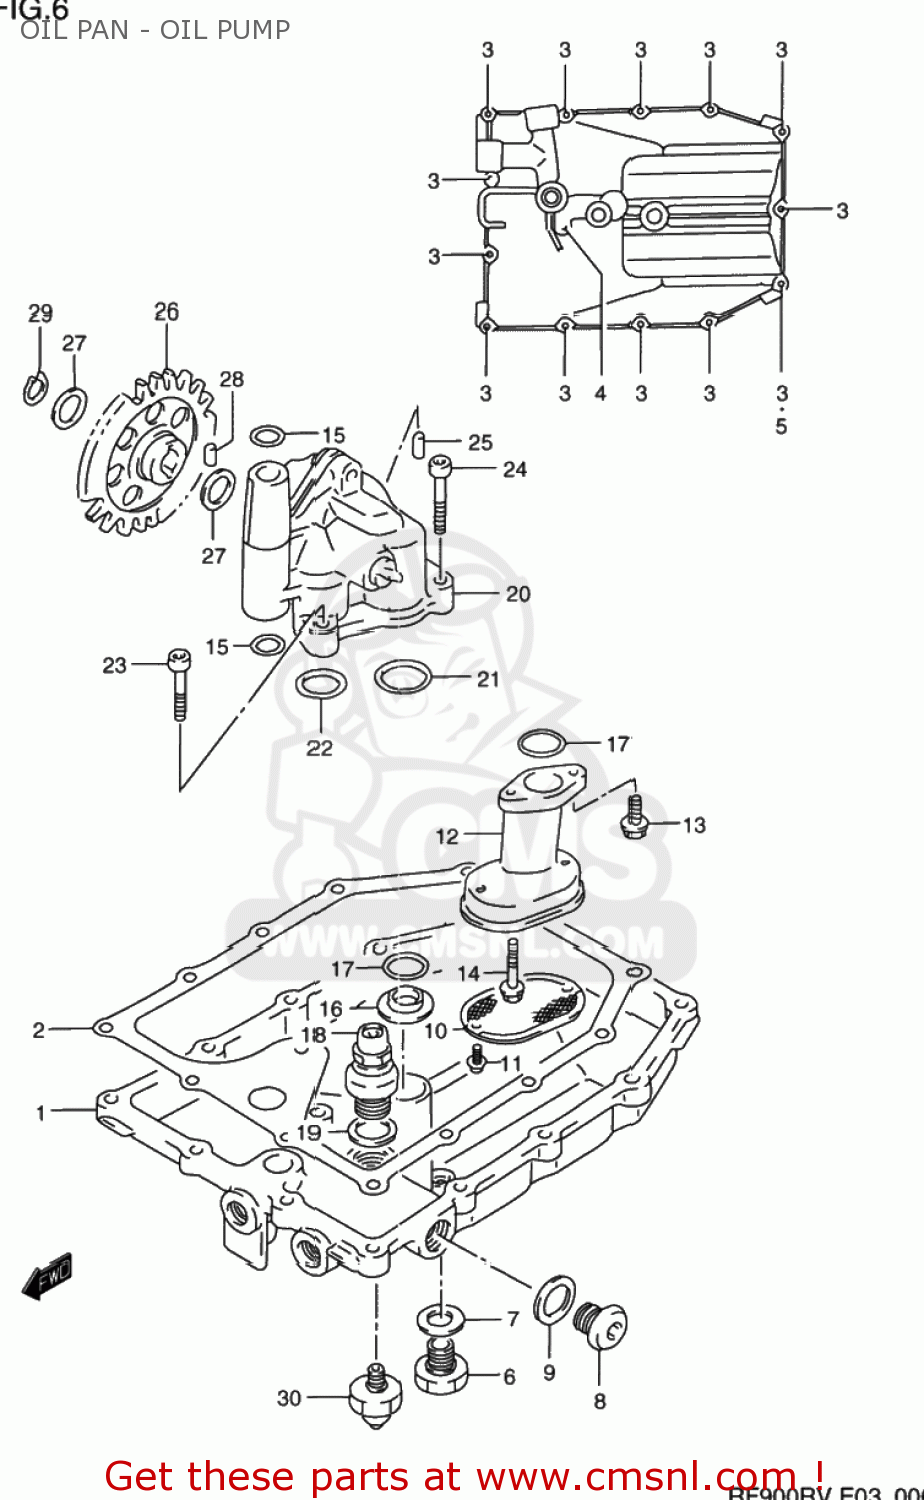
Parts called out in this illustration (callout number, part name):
1	PAN,OIL
2	GASKET,OIL PAN
3	SCREW
4	BOLT
5	GASKET(5.8X11X1.2) (NAS)
6	PLUG
7	GASKET(13.8X18.8X4.8) (NAS)
8	PLUG
9	GASKET(16X22X2) (NAS)
10	STRAINER,ENGINE OIL
11	BOLT
12	PROTECTOR,OIL STRAINER
13	BOLT
14	BOLT, HYDRAULIC UNIT NO.2
15	O RING(D:2.4,ID:11.8)
16	GASKET,OIL OUTLET (NAS)
17	O RING(D:3.2,ID:17.8)
18	VALVE ASSEMBLY,OIL RELIEF
19	GASKET(16X22X2) (NAS)
20	PUMP ASSY,ENGINE OIL
21	O RING(D:2.4,ID:26.2)
22	O RING(D:3.2,ID:17.8)
23	BOLT
24	BOLT
25	PIN
26	GEAR,OIL PUMP DRIVEN(NT:37)
27	SHIM
28	PIN(5X18)
29	CIRCLIP,12 MM
30	SWITCH ASSEMBLY,OIL PRESSURE
